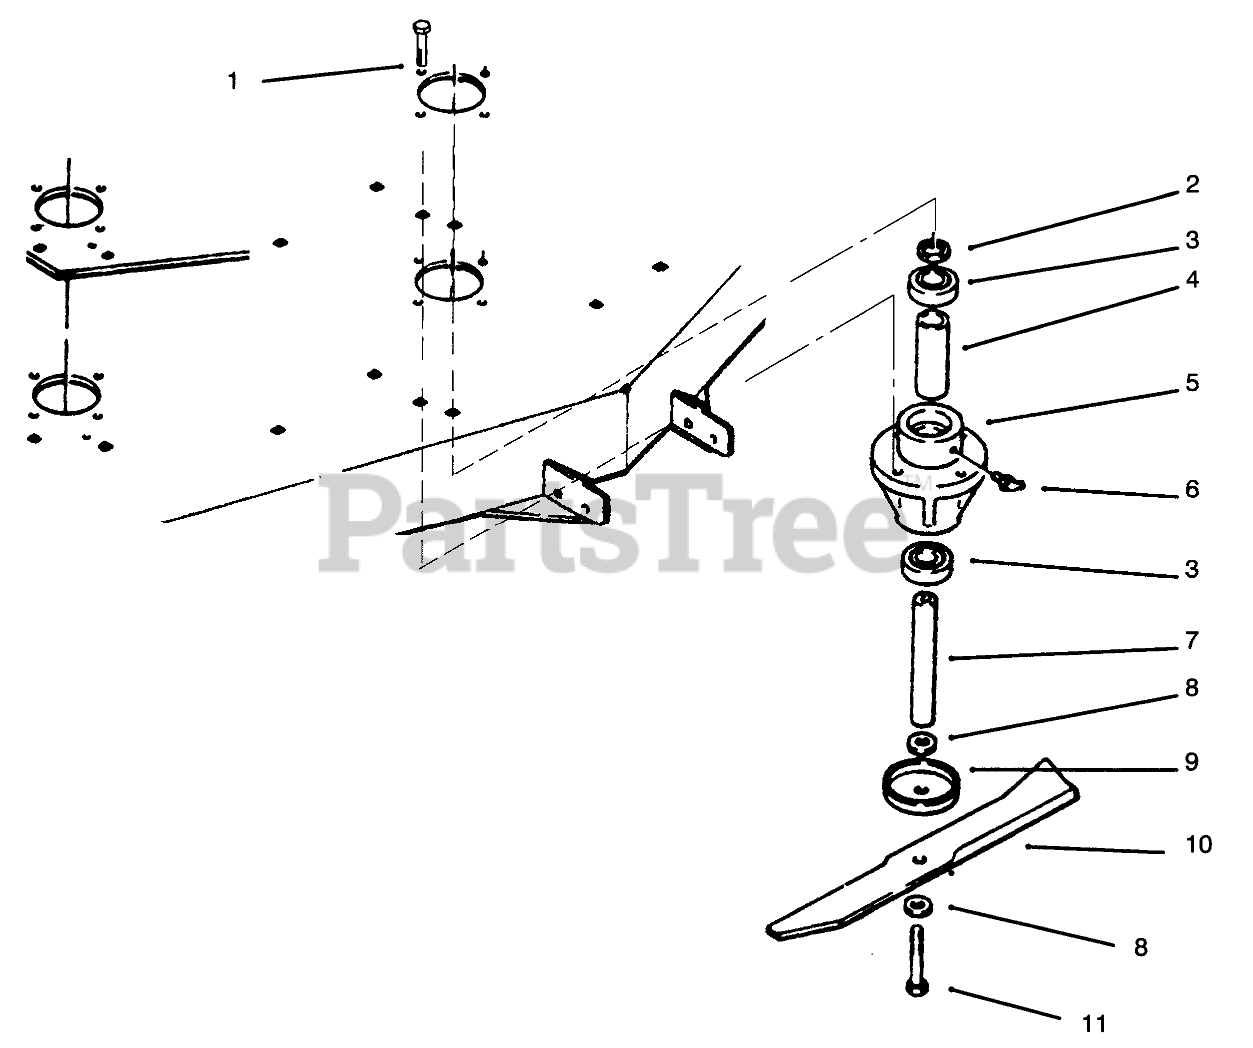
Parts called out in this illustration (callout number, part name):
1	SCREW-HH, LOCK
2	SPACER
3	BEARING-BALL
5	HOUSING-SPINDLE
6	FITTING-GREASE
7	SHAFT-SPINDLE
8	WASHER-SPECIAL
9	CUP-SPINDLE
10	BLADE
11	Bolt
